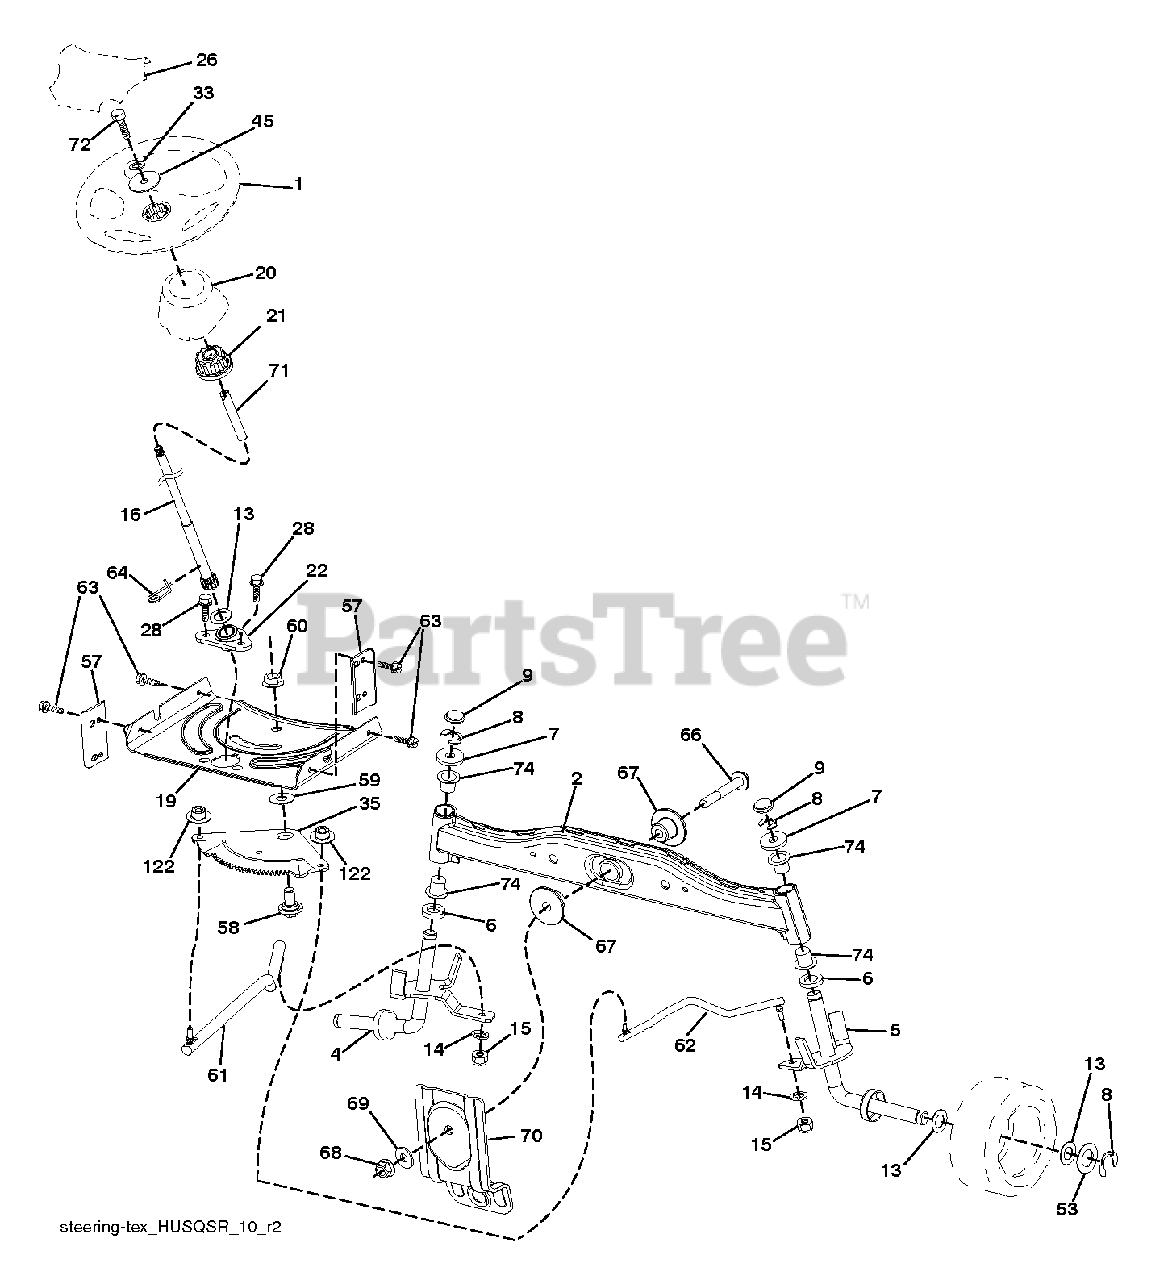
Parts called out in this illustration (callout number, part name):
1	WHEEL.STEER.HUSQ.SR.498.OVMLD
2	AXLE HALF ASM-WELDED
4	SPINDLE.WELDED.LH.15"TEX
5	SPINDLE.WELDED.RH.15"T
6	THRUST WASHER
9	CAP.SPINDLE.BLACK
14	WASHER, LOCK 3/8
15	NUT CROWNLOCK 3/8-24
16	SHAFT.STEER.3/4.PLATED.TEX
19	PLATE.STEER.DDL.NLT/NG
20	STEERING.BOOT.HUSQ.LT
21	ADAPTER, WHEEL STNG..
22	STEERING.SUPT.LOWER.
26	INSERT.CAP.WHL.STRG.HUSQ.PREM
28	SCREW, 3/8-16X3/4
33	LOCKWASHER
35	GEAR.SECTOR.PLATE.DDL.
45	WASHER.11/32
53	WASHER.HARDENED
57	BRACKET.UPSTOP.TEX
58	BOLT.SHOULDER.SECTOR.P
59	WASHER.THURST.SECTOR.S
60	NUT FLANGE LOCK 5/8-11
61	DRAGLINK.LH.BALLSTUD.D
62	DRAGLINK.RH.BALLSTUD.D
63	SCREW
64	RETAINER.CLIP.SPRING.S
66	BOLT HEX FGHD 7/16-14 X 3 SERR
67	BUSHING.PM.FRONT AXLE
68	NUT.LOCK.FLANGE.7/16
69	WASHER.1.5X.505X.118
70	BRKT.DECK.SUSPENSION.F
71	SHAFT.EXTEN.STRG.SPLINE
72	BOLT 5/16-18 X 4 W/PATCH
74	BRNG T
122	CAP.GEAR.SECTOR.TEX
